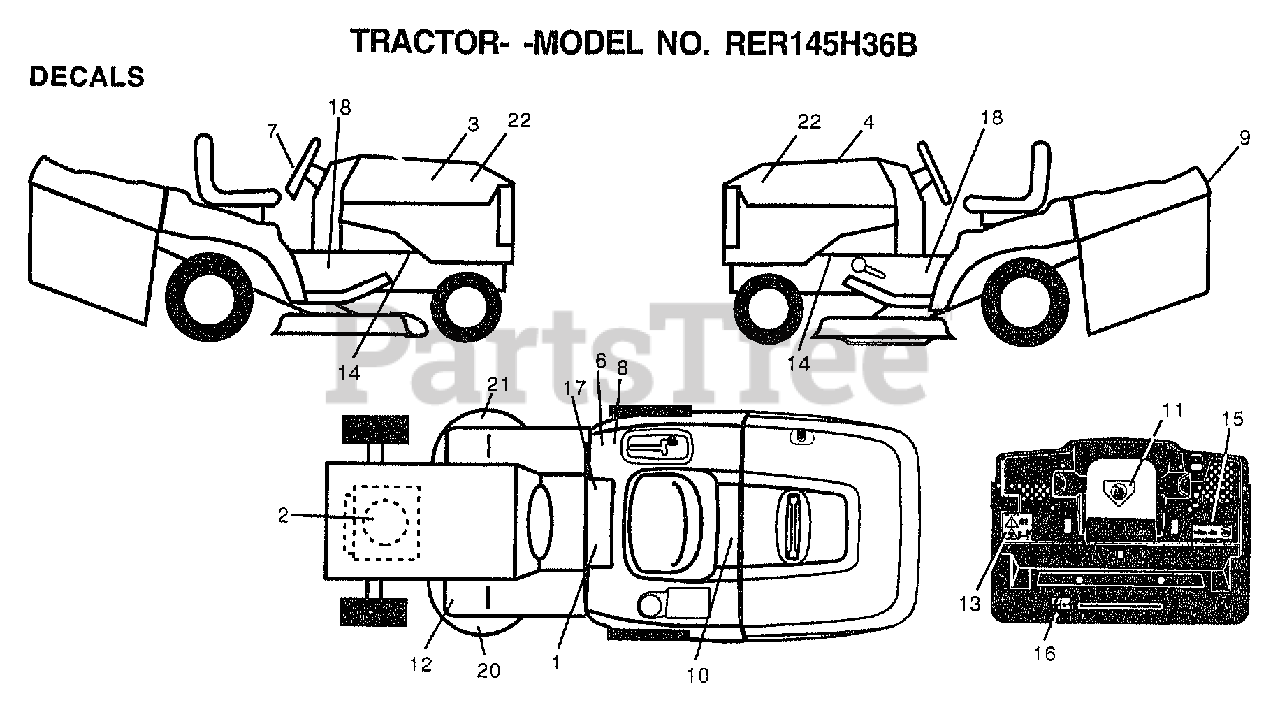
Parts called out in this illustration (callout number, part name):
1	DECAL.READ.O.MANU
2	DECAL, ENGINE
3	DECAL HOOD RH
4	DECAL HOOD LH
7	"DECAL,STR WHL"
8	DECAL.EURO.ST.CE.
9	FENDER DECAL
10	DECAL.BATRY.3-3908
11	DECAL.DANGER.CUTF
12	DECAL-BRAKE/CLUTC
13	DECAL.WARNING.BACKPLATE.CRD
14	"DECAL CHASSIS,HOT"
15	DECAL, OPER BAG
16	DECAL.DRAWBAR.LDL
17	DECAL BRAK PARK
18	DECAL.CHASSIS.HYDRO
21	DECAL.DECK.HEX.BELT
22	DECAL.INS.HD.RALL
